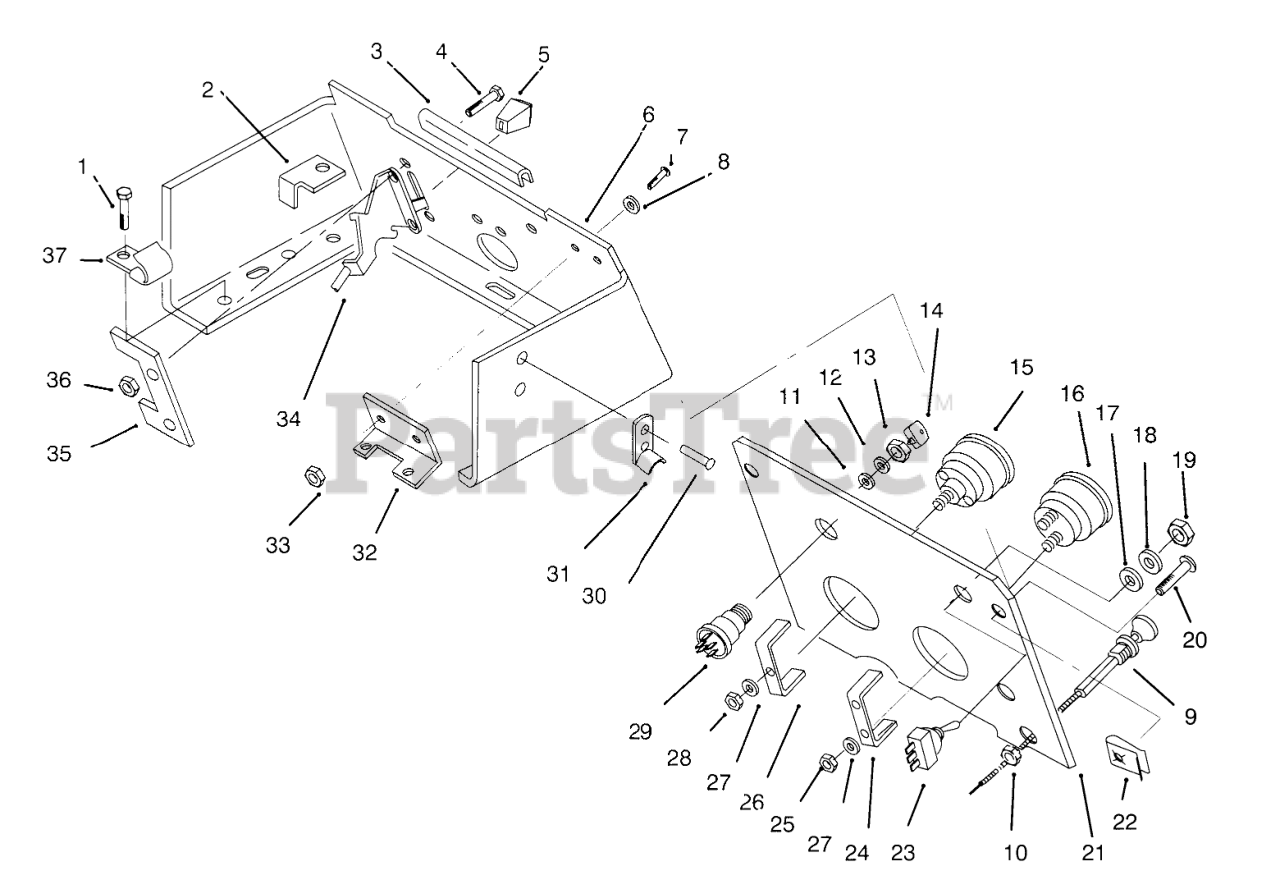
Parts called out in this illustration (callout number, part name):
1	Bolt
2	STOP-PTO
3	EDGING-CONSOLE
4	Screw
6	CONSOLE B
7	SCREW-PAN
8	Washer-Lock
9	CONTROL-CHOKE
10	NUT-HEX PALNUT
11	Washer
12	LOCKWASHER
14	KEY-IGNITION
15	Meter-Hour (Incl. Ref. #27-28)
16	Meter-Volt (Incl. Ref. #24-25)
17	Washer
18	TAB-WASHER
20	SCREW-PPH
21	Plate-Hood Stand
22	CLIP
23	Switch-Light (Incl. Ref. #17-19)
24	CLAMP-MOUNTING
25	HEX NUT 10-32 E.S.
26	CLAMP-HOUR METER
27	WASHER-LOCK
28	NUT-HEX
29	Switch-Ignition (Incl. Ref. #11-13)
30	POPRIVET 1/8X 1/8 BK
31	KEEPER-LATCH
32	BRACKET
33	Nut
34	CONTROL-THROTTLE
35	Washer
36	Nut
37	J-CLIP
